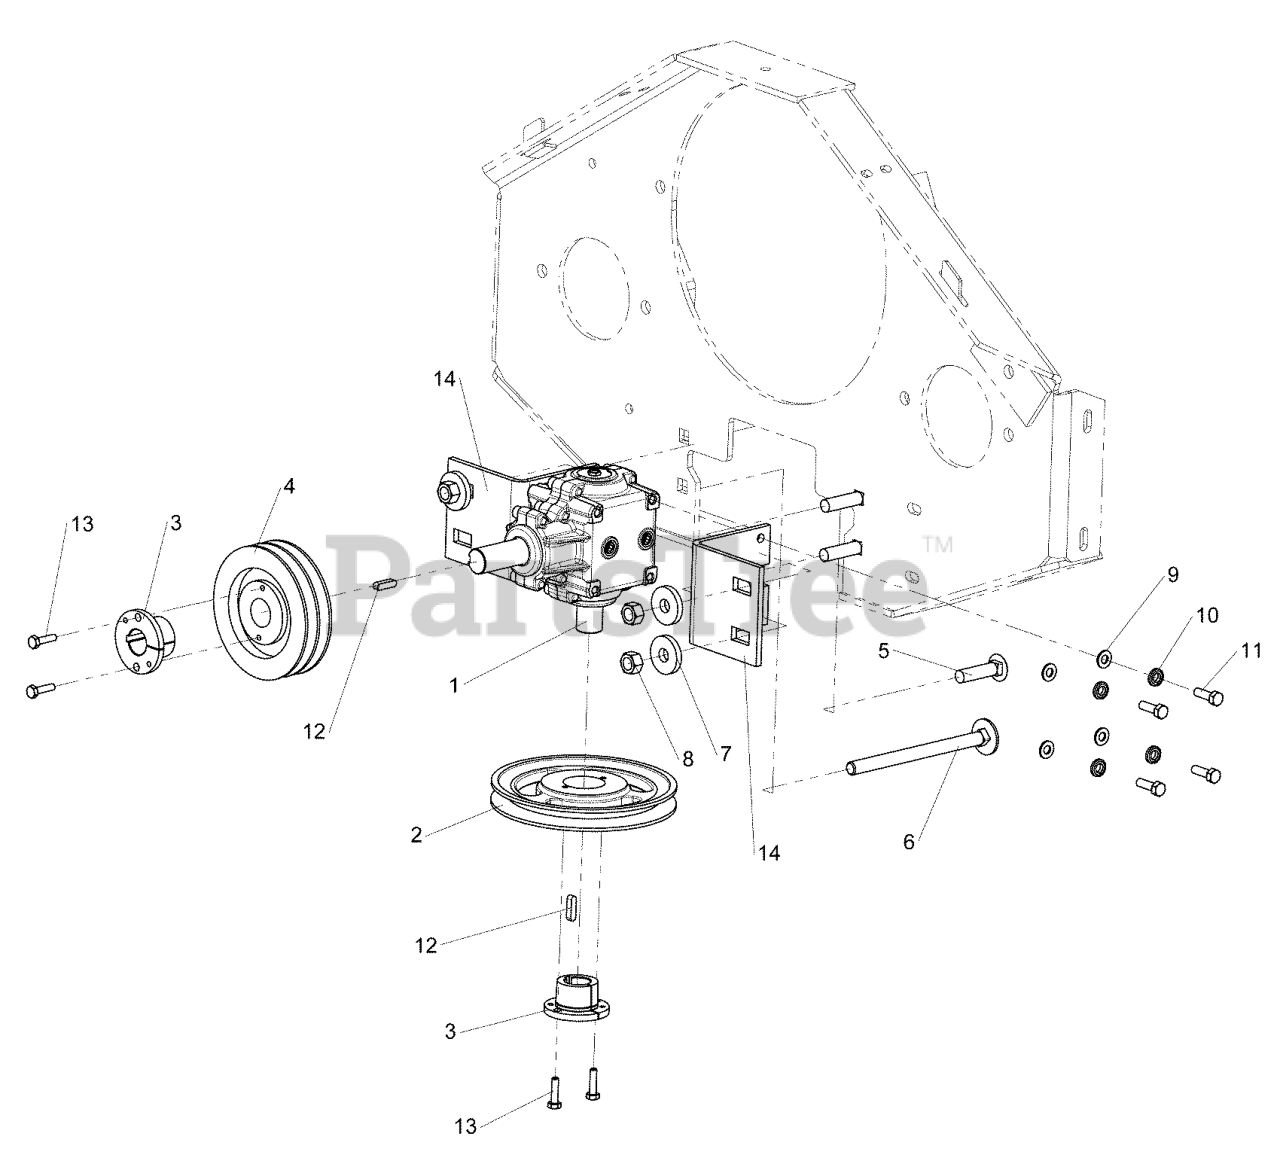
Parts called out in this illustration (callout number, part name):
1	GEARBOX, RIGHT ANGLE, 1:1
2	PULLEY, SPINDLE, BH72
3	BUSHING, TAPERED HUB
4	PULLEY, GEARBOX INPUT
5	BOLT, 1/2-13 X 2", CARRIAGE
6	BOLT, 1/2-13 X 7", CARRIAGE
7	WASHER, FRAME RETAINING
8	NUT, 1/2-13 HEX NYLON LOCK
9	WASHER, 5/16" SAE
10	WASHER, 5/16 LOCK CZ
11	BOLT, 5/16-18 X 1" GD5 YZ
12	KEY, .250 SQ. X 1, ROUND END
13	BOLT, 1/4-20 X 1" GD5 CZ
14	WELD, MOUNT, GEAR BOX - RED
